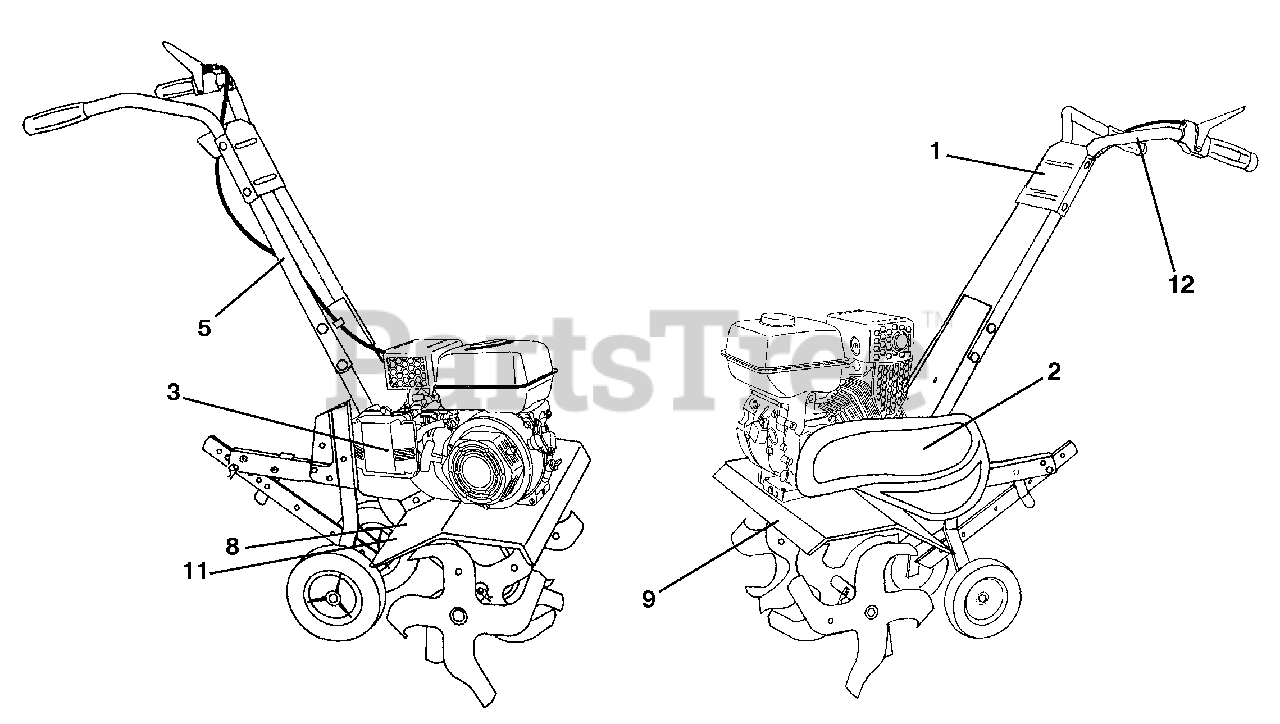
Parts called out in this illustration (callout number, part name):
1	Decal, Poulan Pro
2	Decal, Belt Guard
3	Decal, Air Cleaner
5	Decal, Hand Placement
8	Decal, Warning
9	Decal, Heavy Duty
11	Decal, Warning, Rotating Tines
12	Decal, Control Tine
12	Manual, Operator's, English/French
12	Manual, Repair Parts
